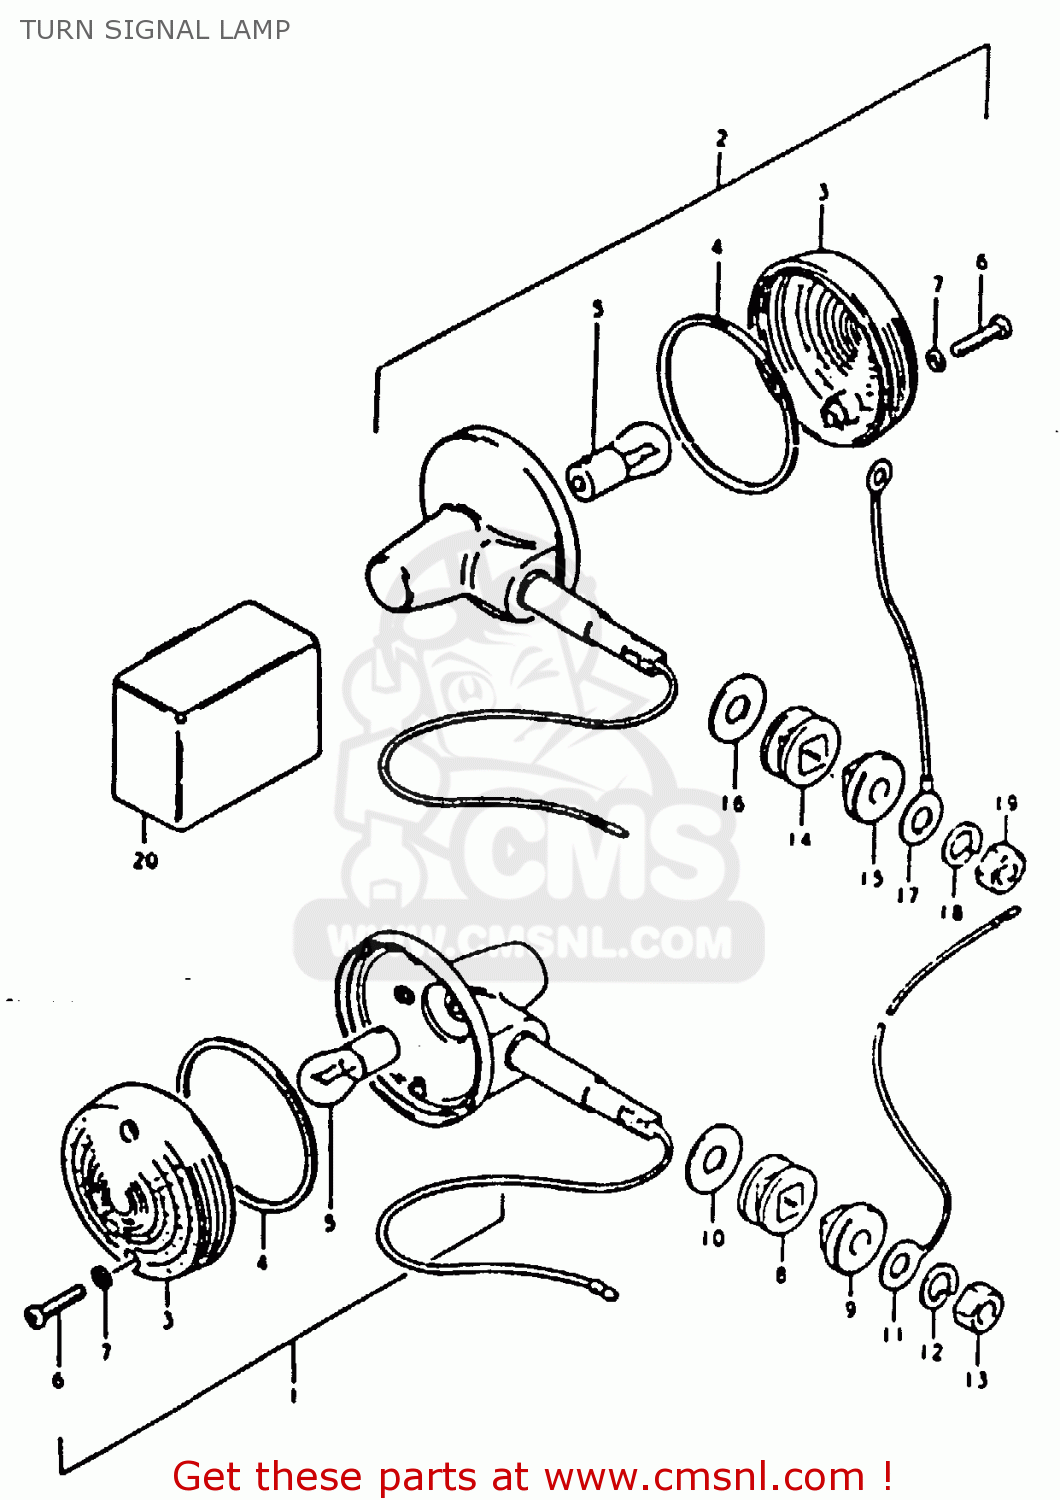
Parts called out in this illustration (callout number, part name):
1	LAMP, REAR TURN SIGNAL
2	LAMP, REAR TURN SIGNAL
3	LENS
4	GASKET (NAS)
5	BULB(6V8W,STANLEY,A4115)
6	SCREW
7	GASKET (NAS)
8	CUSHION
9	SPACER,RR TURNSIGNAL LAMP
10	WASHER (10.5X30X2.3)
11	LEAD WIRE,EARTH
12	LOCK WASHER
13	NUT
14	CUSHION
15	SPACER,RR TURNSIGNAL LAMP
16	WASHER (10.5X30X2.3)
17	LEAD WIRE
18	LOCK WASHER
19	NUT
20	RELAY, TURN SIGNAL
